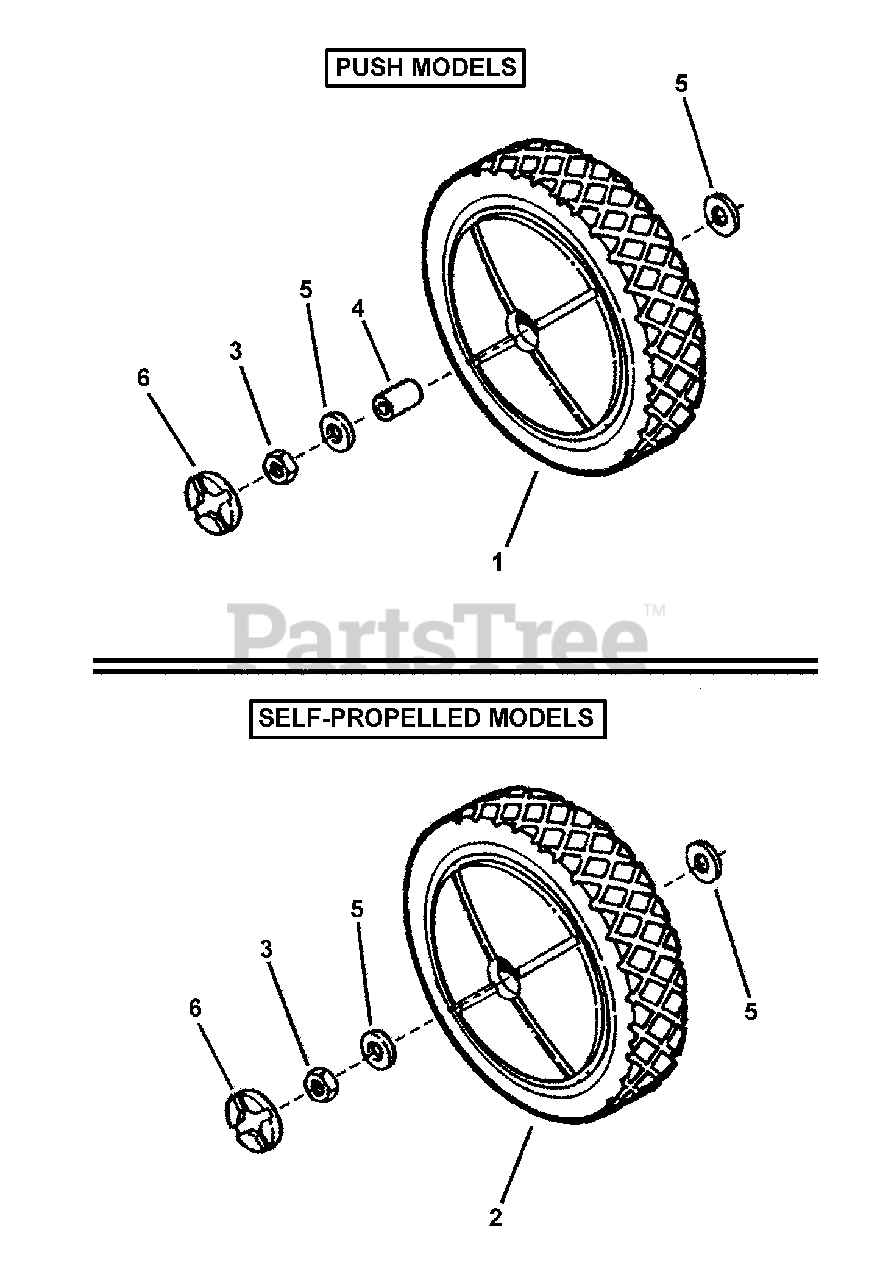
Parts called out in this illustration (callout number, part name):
1	WHEEL, 10 x 1.75" Plastic (Push Models)
2	WHEEL, 10 x 1.75" Plastic (Self-Propelled Models)
3	NUT, 7/16-20 Hex Center Lock Jam
4	BUSHING, Axle
5	WASHER, 7/16" Flat
6	PLUG, Wheel
